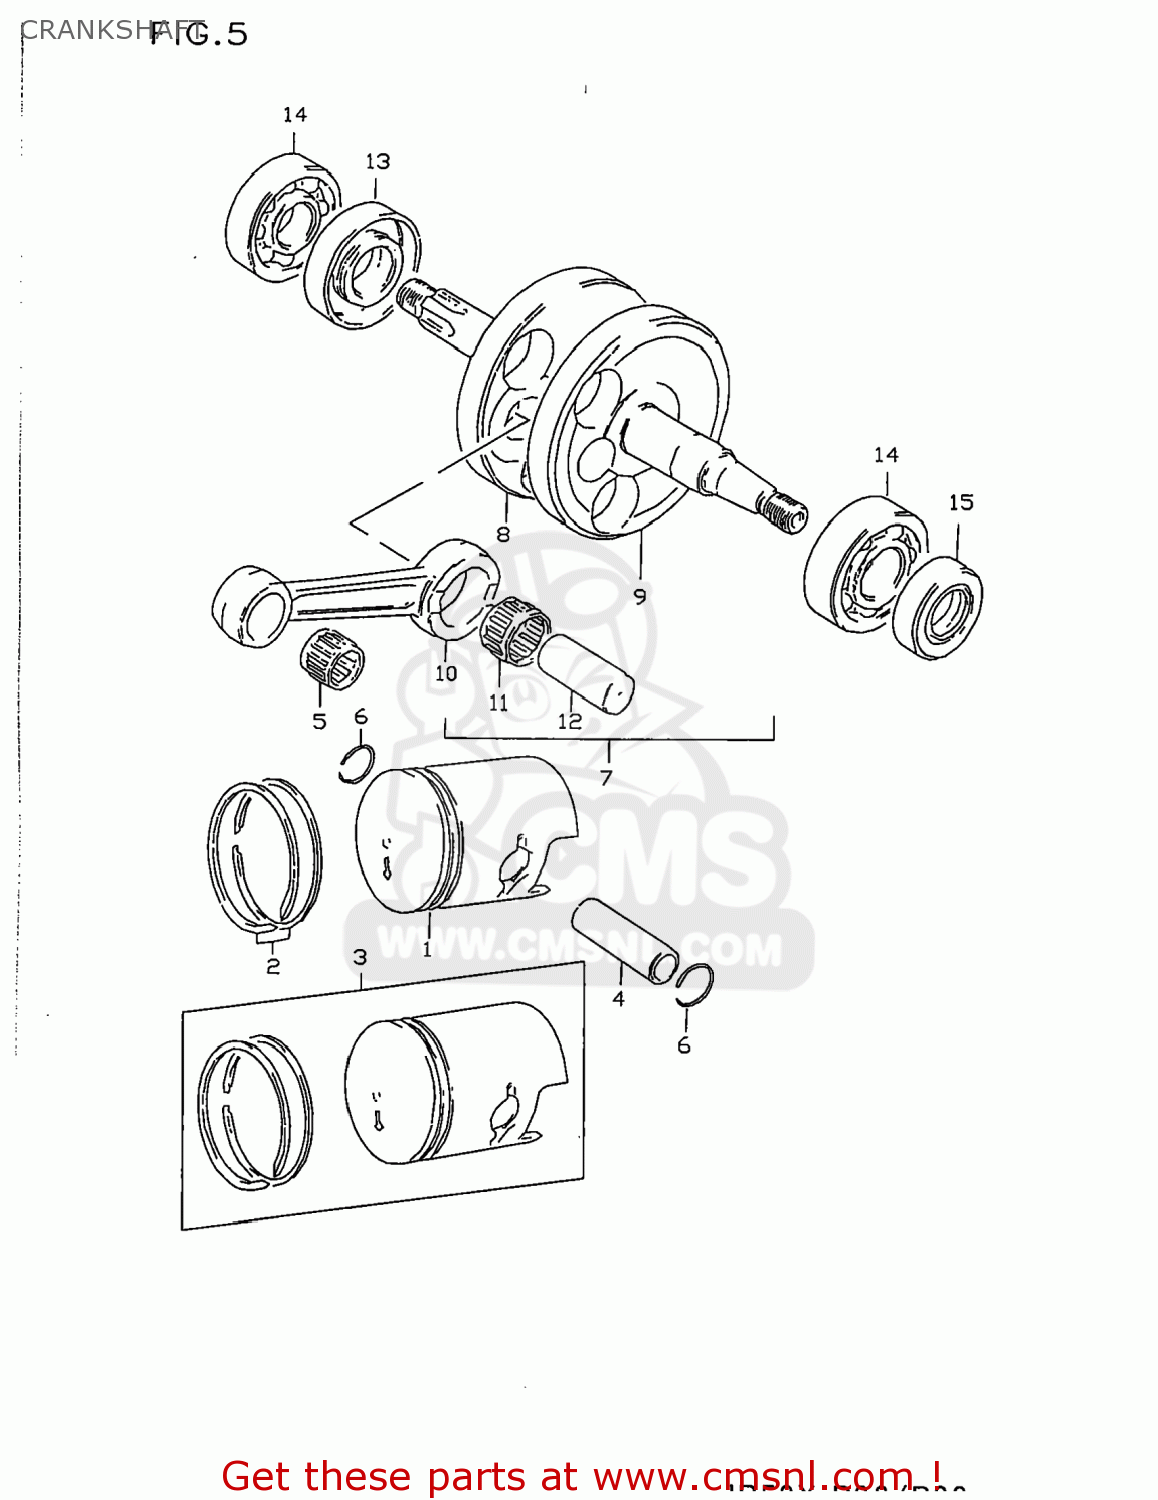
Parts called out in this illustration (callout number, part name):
1	PISTON
2	RING SET,PISTON
3	PISTON SET (OS:0.5)
4	PIN,PISTON
5	BEARING(12X16X16)
6	RING,SNAP
7	CRANKSHAFT ASSY
8	CRANKSHAFT,R
9	CRANKSHAFT,L
10	ROD,CONNECTING
11	BEARING(15X21X9.8)
12	PIN,CRANK
13	SEAL,OIL(22X40X8)
14	BEARING(17X40X12)
15	OIL SEAL (17X29X7)
